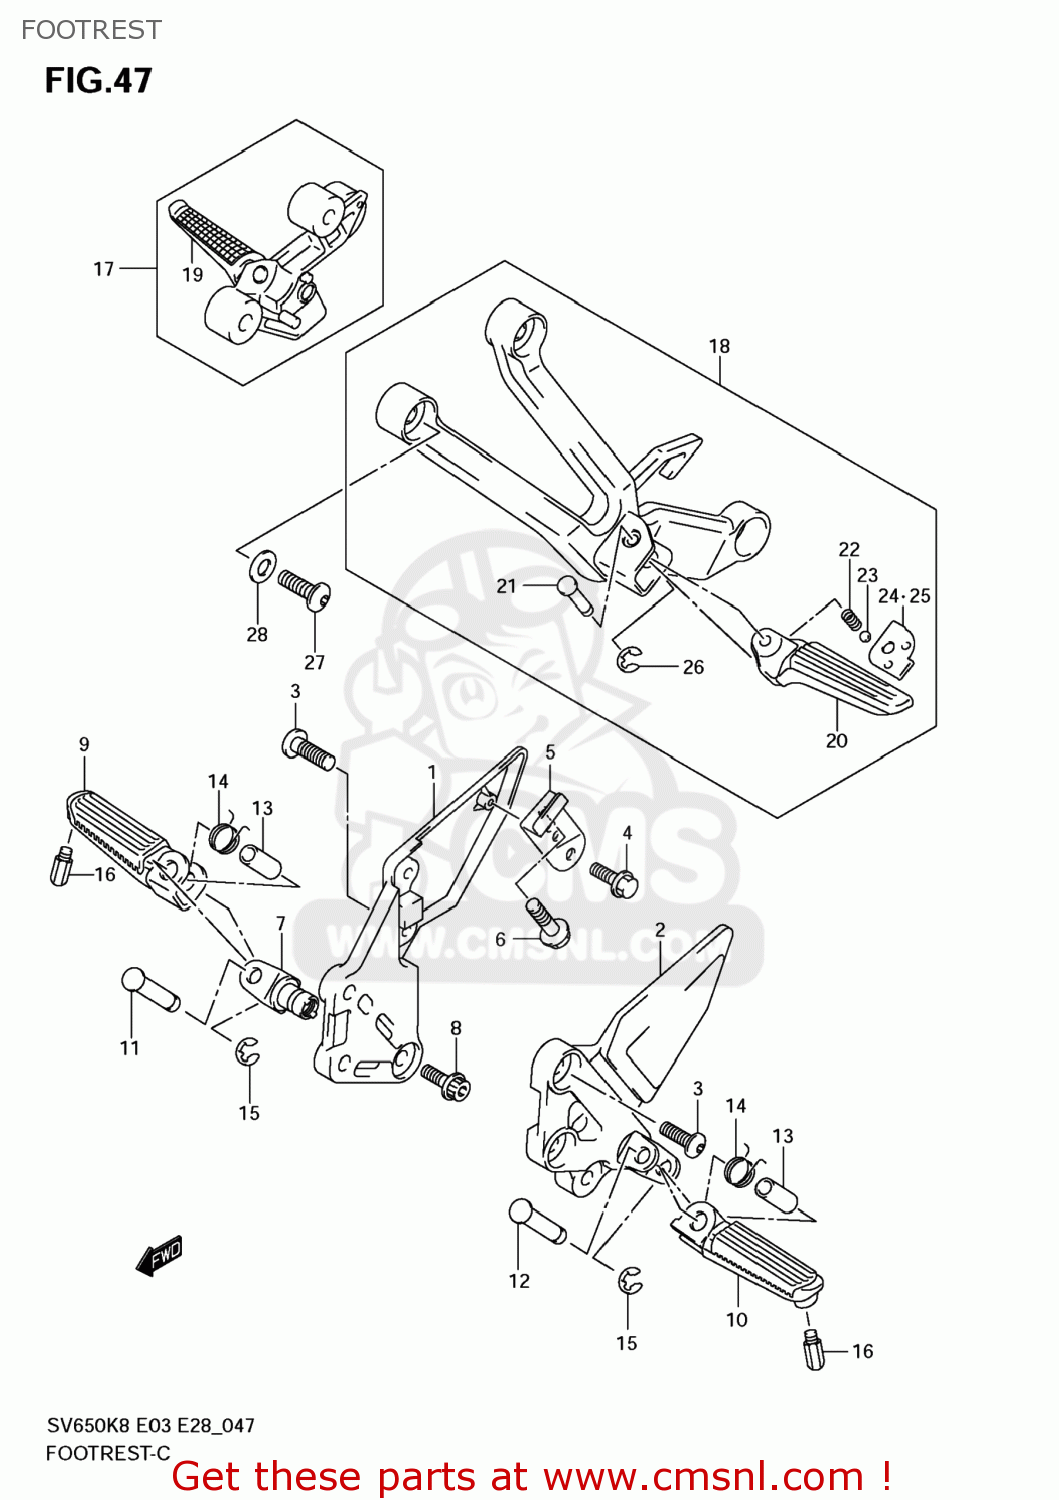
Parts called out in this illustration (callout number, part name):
1	BRACKET,FR FOOTREST,R
2	BRACKET,FR FOOTREST,L
3	BOLT(8X20)
4	BOLT
5	REINF,FOOTREST BRACKET
6	BOLT
7	HOLDER,FOOTREST,R
8	BOLT(10X28)
9	BAR,FR FOOTREST,R
10	BAR,FR FOOTREST,L
11	PIN
12	PIN
13	SPACER(8.1X12X22)
14	SPRING
15	E RING
16	BOLT,BANK SENSOR
17	FOOTREST ASSY,PILLION
18	FOOTREST ASSY,PILLION
19	BAR,PILLION FOOTREST,R
20	BAR,PILLION FOOTREST,L
21	PIN
22	SPRING
23	BALL
24	PLATE,PILLION FOOT,R
25	PLATE,PILLION FOOT,L
26	E RING
27	BOLT(8X23)
28	WASHER
